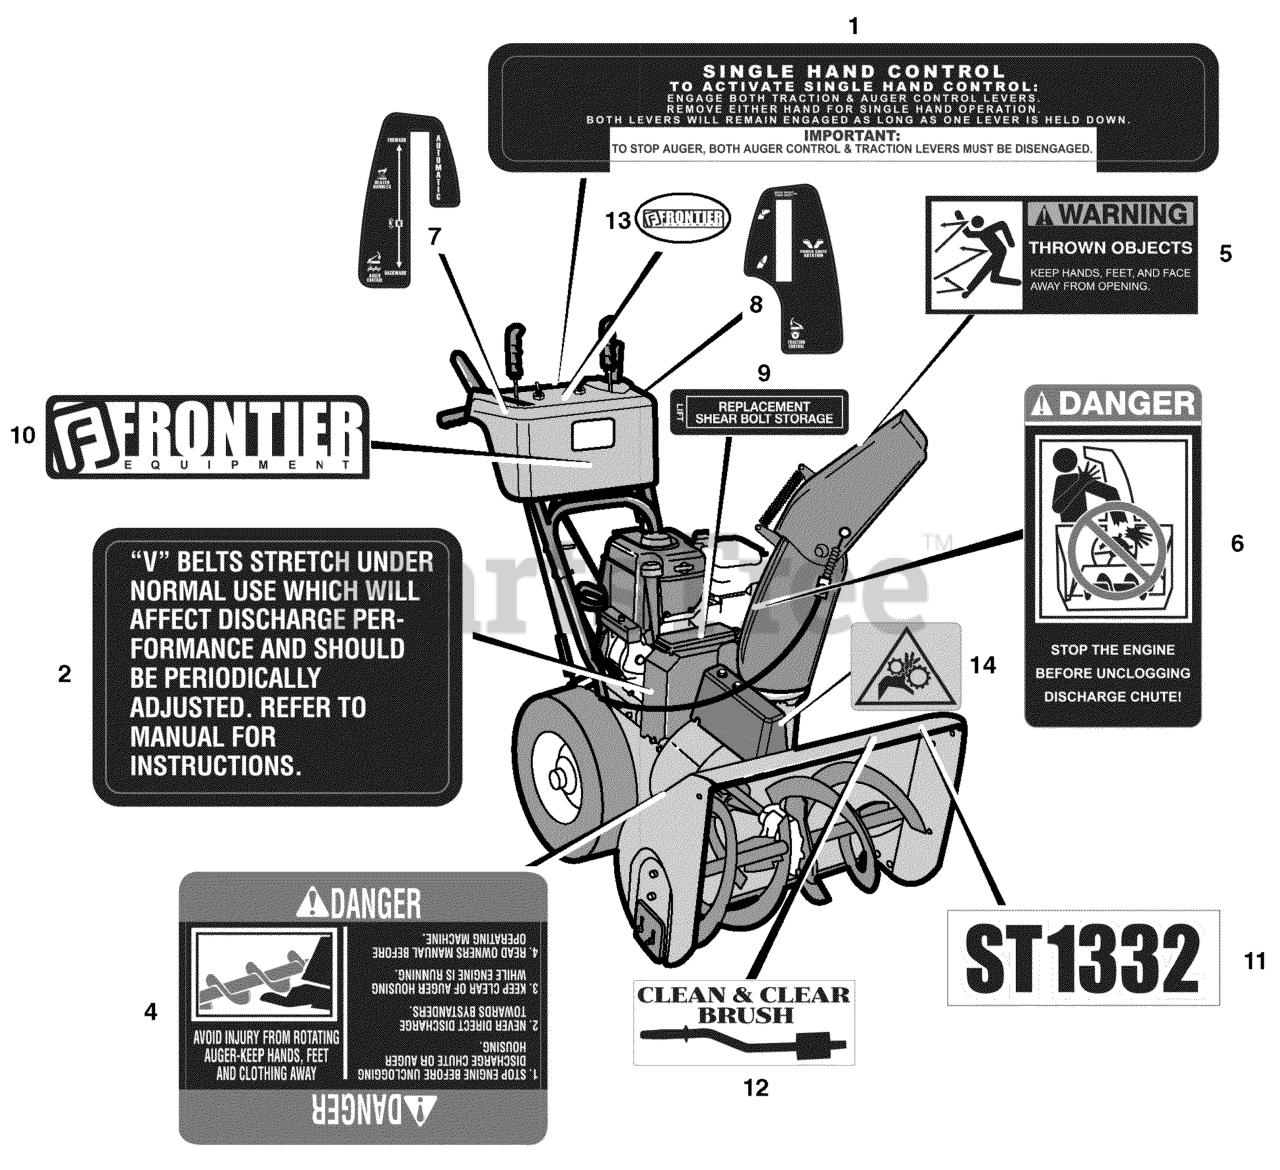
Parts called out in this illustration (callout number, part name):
1	DECAL, SINGLE HAND CONTROL
2	DECAL, V-BELTS
4	DECAL, ROTATING AUGER
5	DECAL, THROWN OBJECT
6	DECAL, UNCLOGGING CHUTE
7	DECAL, SPEED CONTROL
8	DECAL, REMOTE CHUTE CONTROL
9	DECAL, SHEAR BOLTS
10	LOGO NAMEPLATE, FRONTIER
11	DECAL, ST1332
12	DECAL, CLEAN & CLEAR BRUSH
13	DECAL, FRONTIER -CIRCLE
14	DECAL, PINCH POINT - ELECTRIC CHUTE
